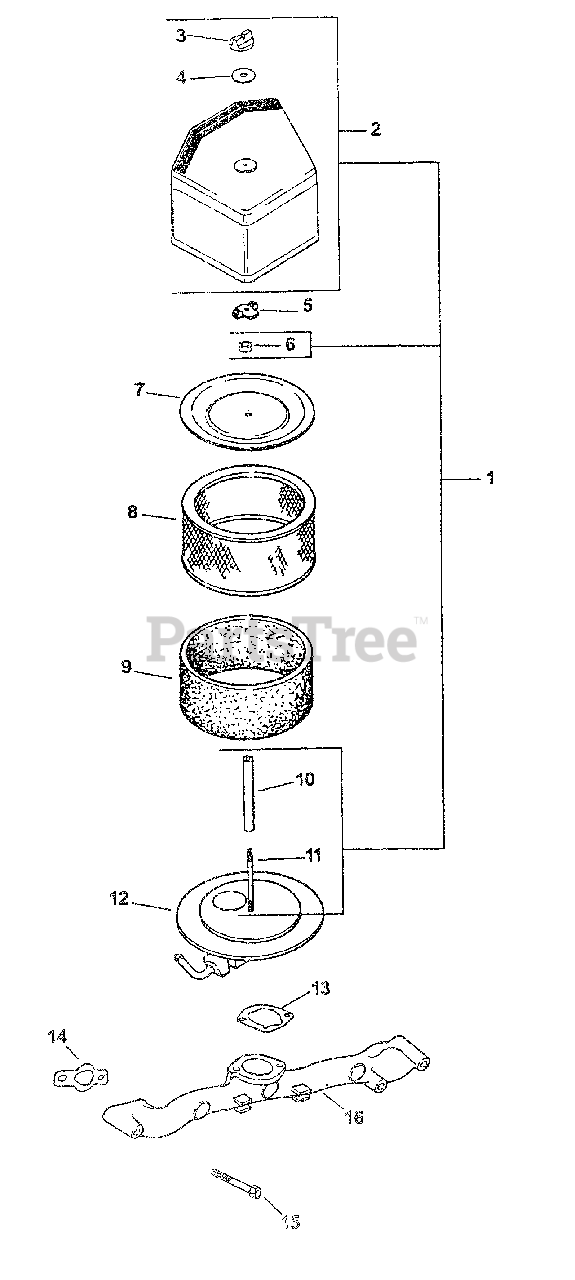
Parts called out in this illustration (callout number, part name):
1	Kit, Air Cleaner
2	Kit, Air Cleaner Cover
4	Gasket, Air Cleaner Cover Knob
6	Nut, Hex Flange
7	Cover, Air Cleaner Element
8	Element, Air Cleaner
9	Precleaner, Element
12	Elbow, Air Cleaner
13	Gasket, Air Cleaner Base
14	Gasket, Intake Manifold
15	Screw, Hex Flange
16	Manifold, Intake
